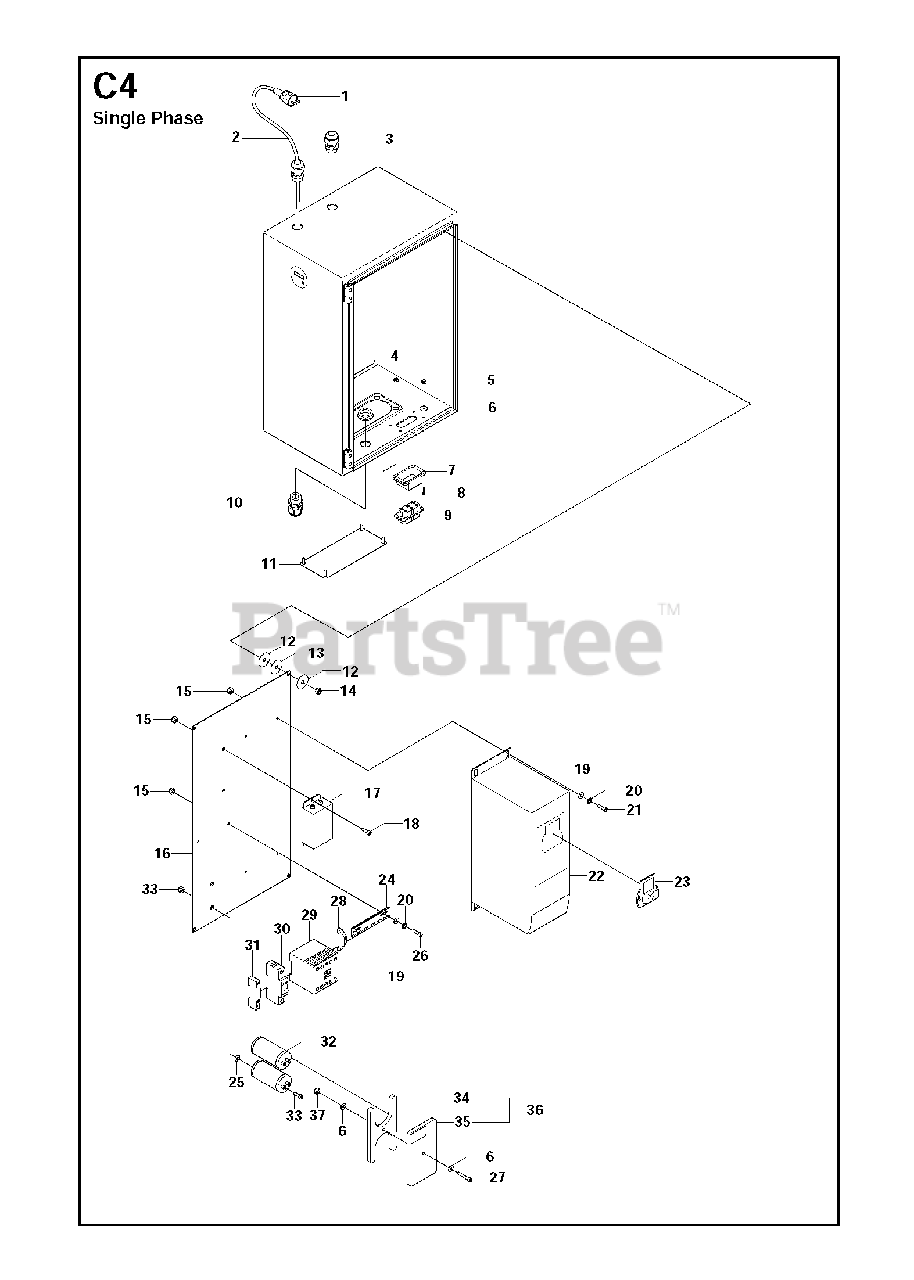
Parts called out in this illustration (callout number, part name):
4	HEXAGON LOCKING NUT
5	HEXAGON LOCKING NUT
14	HEXAGON LOCKING NUT
21	SCREW IHSCM
